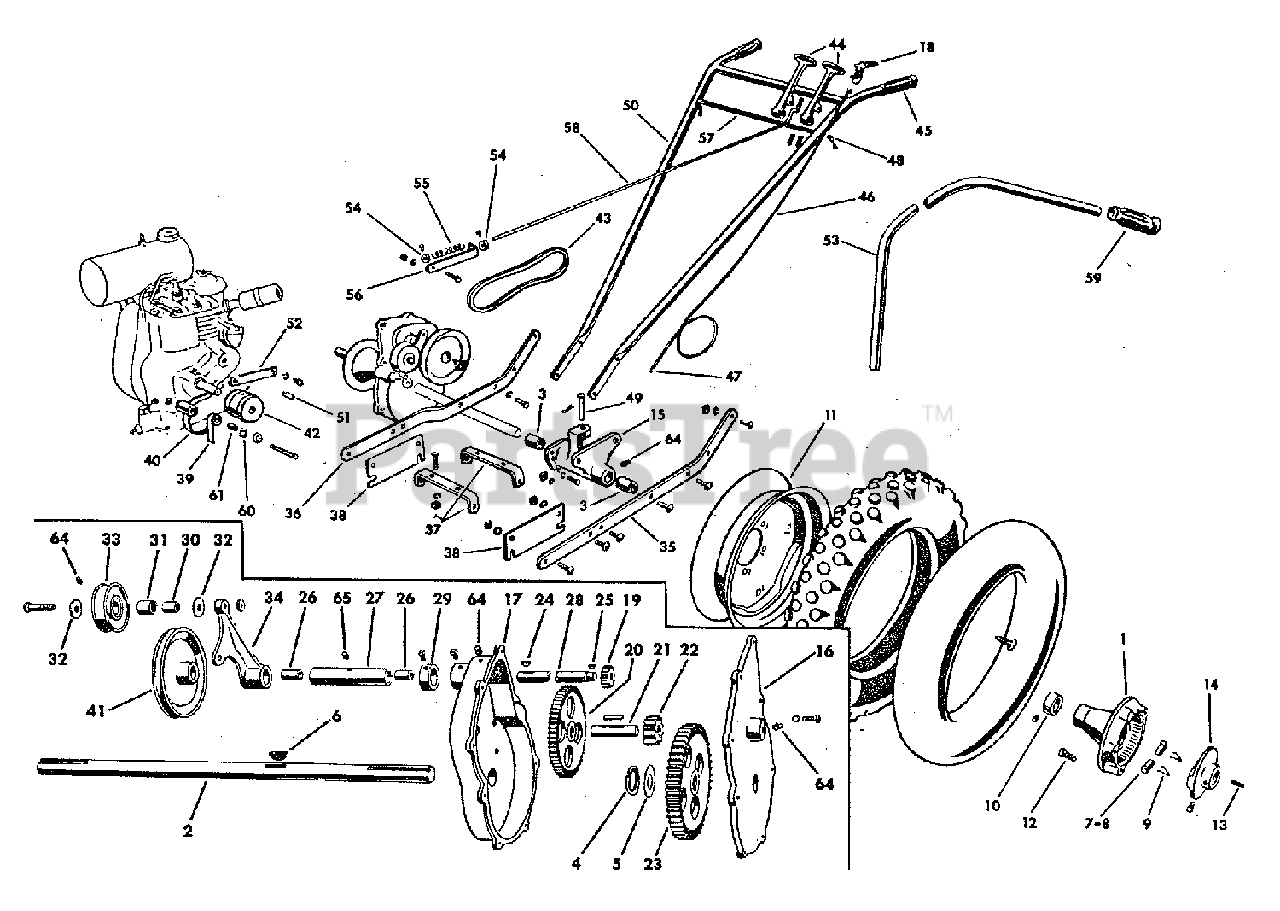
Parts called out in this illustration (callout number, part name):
1	HUB, Wheel
4	RING, Retaining
7	RATCHET DOG, Left
8	RATCHET DOG, Right
10	COLLAR, Set, 1"
11	WHEEL, Drive
12	BOLT, Hub
14	CAGE, Ratchet
15	FRAME BRACKET W/BUSHINGS
16	COVER, Gear Case
17	CASE, Gear
18	LEVER ASSEMBLY, Throttle Control
19	REDUCTION PINION, 12-Teeth, 1/2" Face
20	REDUCTION GEAR, 60-Teeth, 1/2" Face
21	SHAFT, Intermediate
22	PINION, 10-Teeth, 3/4" Face
23	DRIVE GEAR, 50-Teeth, 3/4" Face
27	BEARING, Housing w/Bushings
28	SHAFT, Pulley
29	COLLAR, Set, 15/16"
30	BEARING RACE, Inner
31	BEARING, Idler Pulley
32	THRUST WASHER, Idler Pulley
33	PULLEY, Idler
34	ARM, Idler
35	FRAME SIDE MEMBER, Left
36	FRAME SIDE MEMBER, Right
37	BRACKET, Engine Mounting
38	PLATE, Hitch
39	HOLDER, Belt
40	GUIDE, Belt
41	SHEAVE, Transmission
42	PULLEY, Engine
43	BELT, Drive, 34"
44	LEVER, Clutch
45	HANDLE, Rubber Grip, 7/8"
46	WIRE HOUSING, Throttle Control
47	WIRE, Throttle Control
48	CLAMP, Flexible Cable
49	PIN, Draw Bar
50	HANDLE, Tractor
52	BRACKET, Belt Guide
53	HANDLE, Control
54	SET COLLAR, Idler Rod
56	END, Idler Rod
57	SHAFT, Lever
58	ROD, Idler
59	HANDLE GRIP, 3/4"
60	WASHER, Spring Tension
61	BUSHING, Belt Stop
62	TOOL KIT
63	GUN, Grease
